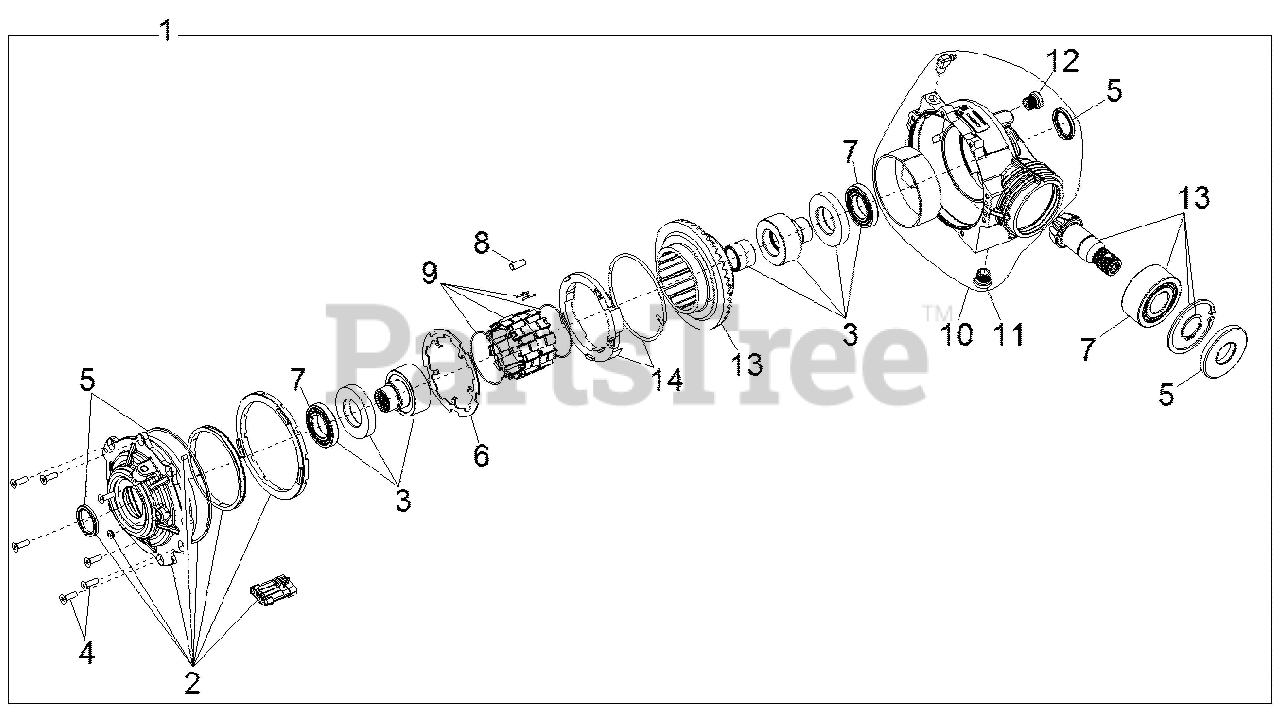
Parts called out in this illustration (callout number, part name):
1	ASM-GEARCASE,FRONT 12 POCKET
2	ASM-COVER,OUTPUT
3	KIT-HUB,ASM
4	KIT-FASTENER
5	KIT-SEAL REPAIR
6	PLATE-4WD ARMATURE
7	BEARING-PINION,5306
8	KIT-ROLLER (20)
9	K-CLUTCH ROLLS
9	ASM-ROLL CAGE
10	KIT-GEARCASE ASM
11	DRAIN PLUG(6203-95-010)
12	FILL PLUG(1300-04-001-T)
13	K-GEAR HOUSING & PINION
14	K-TORSION SPRING & RETAINER
